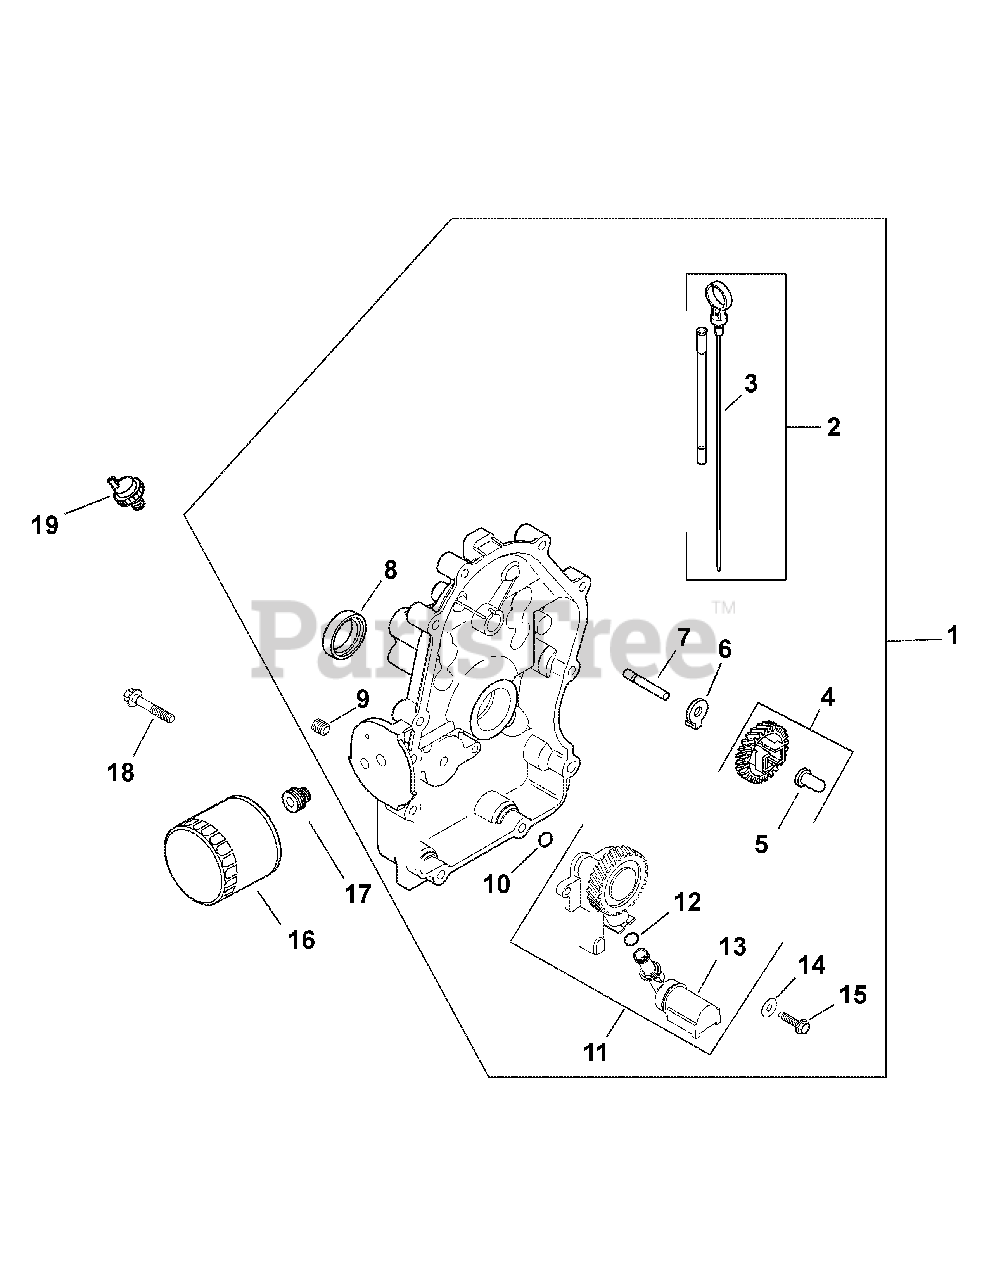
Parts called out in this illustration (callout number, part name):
1	Closure Plate Assembly
2	Kit, Dipstick/ Tubes
4	Kit, Governor Gear w/Pin
5	Pin, Governor Regulating
7	Shaft, Governor Gear
9	Plug, Ctsk Pipe, 1/8"
11	Kit, Oil Pump Ass’y
12	O-Ring, Oil Pick-up
13	Pick-up, Oil
14	Washer, Flat 6 mm
15	Screw, Flg Thd Frm M6x1.0x25
17	Nipple, Oil FIlter
18	Screw, Flg M8 x 1.25 x 45
19	Switch, Oil Pressure
